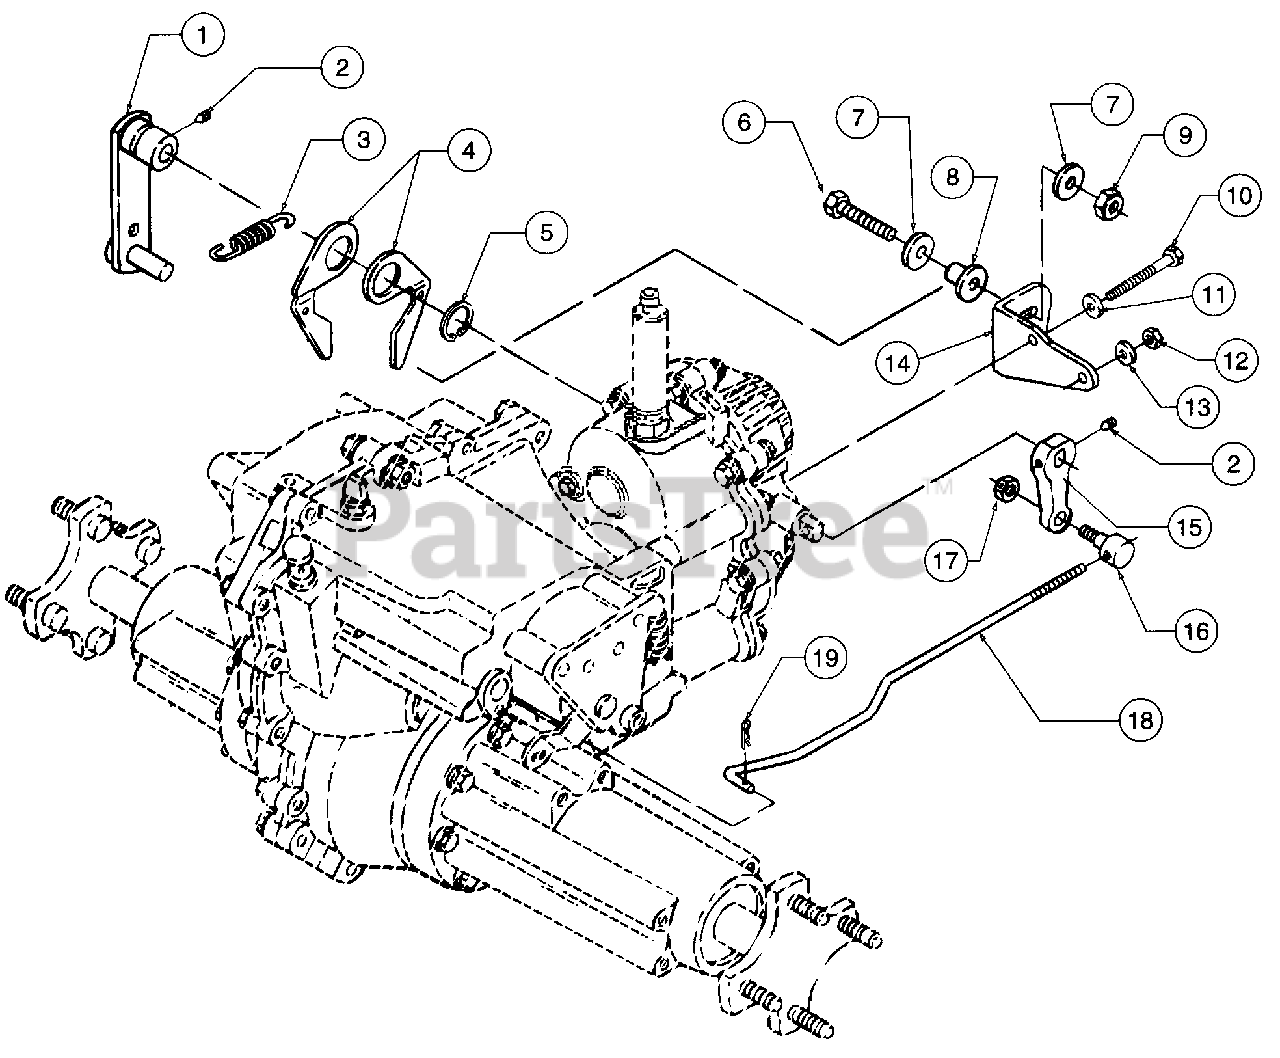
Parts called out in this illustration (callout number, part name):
1	Arm Assy, Control
2	Screw w/Patch, Set
3	Spring, Extension, .477 OD x 1.68 Lg
4	Arm, Neutral
5	Ring, Snap, .8975 Shaft
6	Screw, Hex Cap, 1/4-20 x 1.25
7	Washer, Flat, .25 x .93 x .120
8	Spacer, Centering
9	Nut, Hex Top Lock, 1/4-20
10	Screw, Hex Cap, 5/16-18 x 4.0
11	Washer, Lock, 5/16
12	Nut, Hex Center Lock, 1/4-20
13	Washer, Flat, .25 x .62 x .052
14	Bracket, 6-Speed Neutral
15	Arm, Clutch/Brake
16	Ferrule, 5/16-24 Thrd
17	Nut, Hex Center Lock Jam, 5/16-24
18	Rod, Shift Interlock
19	Pin, Internal Cotter
